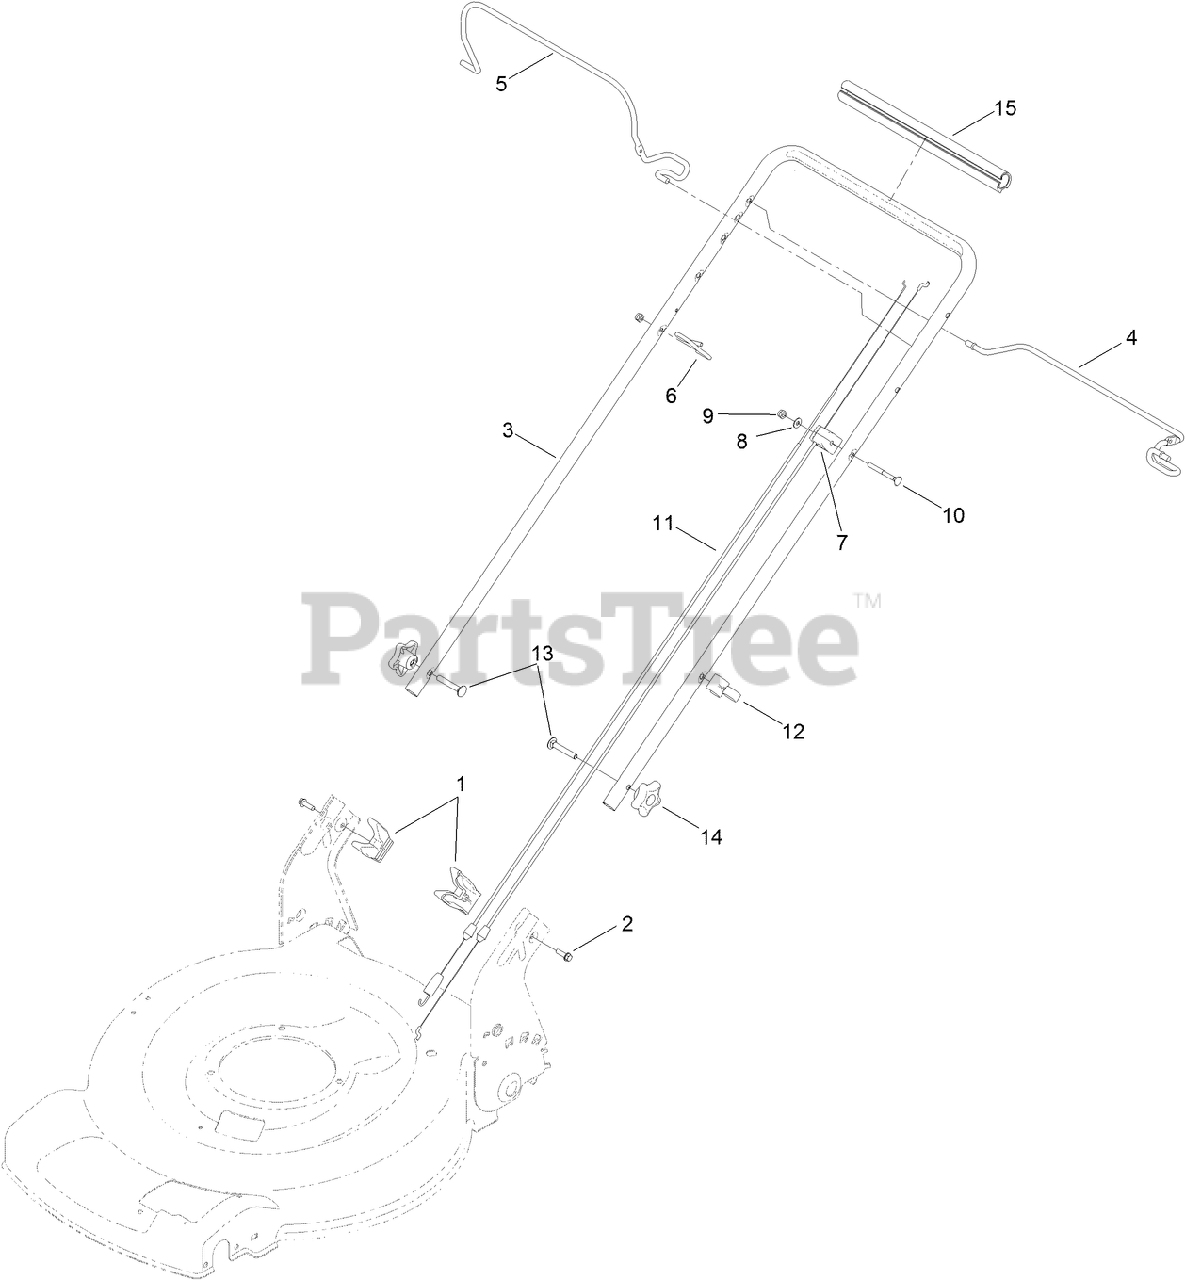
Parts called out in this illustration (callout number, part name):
1	ANCHOR-BAG
2	SCREW-HWH
4	BAIL-TRACTION
5	BAIL-BRAKE
6	GUIDE-ROPE
7	CABLE-BRAKE
8	WASHER-FLAT
9	NUT-LOCK, NI
10	SCREW-HANDLE
11	CABLE-TRACTION
12	GUIDE-CABLE
13	BOLT-CARR
14	KNOB-HANDLE
15	GRIP-HANDLE, COMFORT
